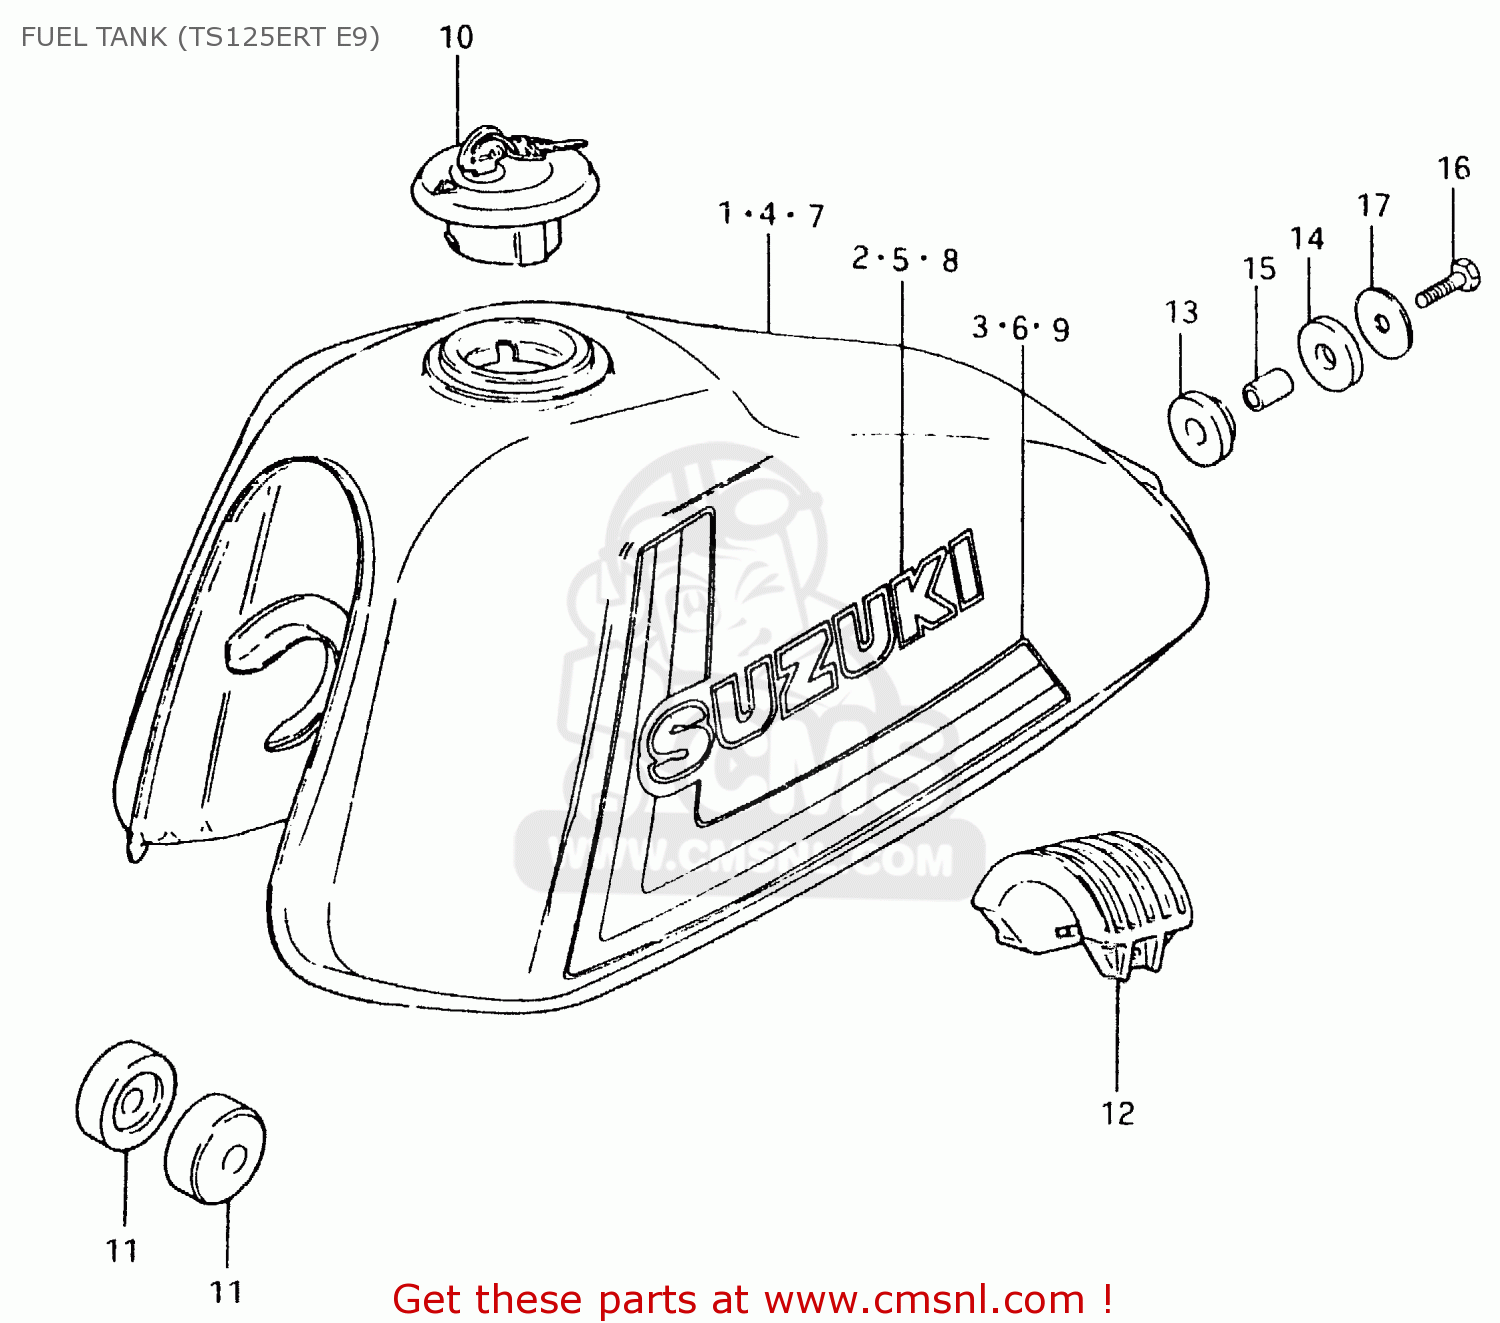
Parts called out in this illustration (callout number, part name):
1	TANK, FUEL (RED)
2	EMBLEM
3	TAPE SET
4	TANK, FUEL (BLUE)
5	EMBLEM
6	TAPE SET
7	TANK, FUEL (WHITE)
8	EMBLEM(BLACK)
9	TAPE SET
10	CAP SET,FUEL TANK
11	CUSHION
12	CUSHION,FUEL TANK
13	CUSHION
14	CUSHION
15	SPACER(8.5X12X19)
16	BOLT (8X30)
17	WASHER (8.5X29X1.6)
